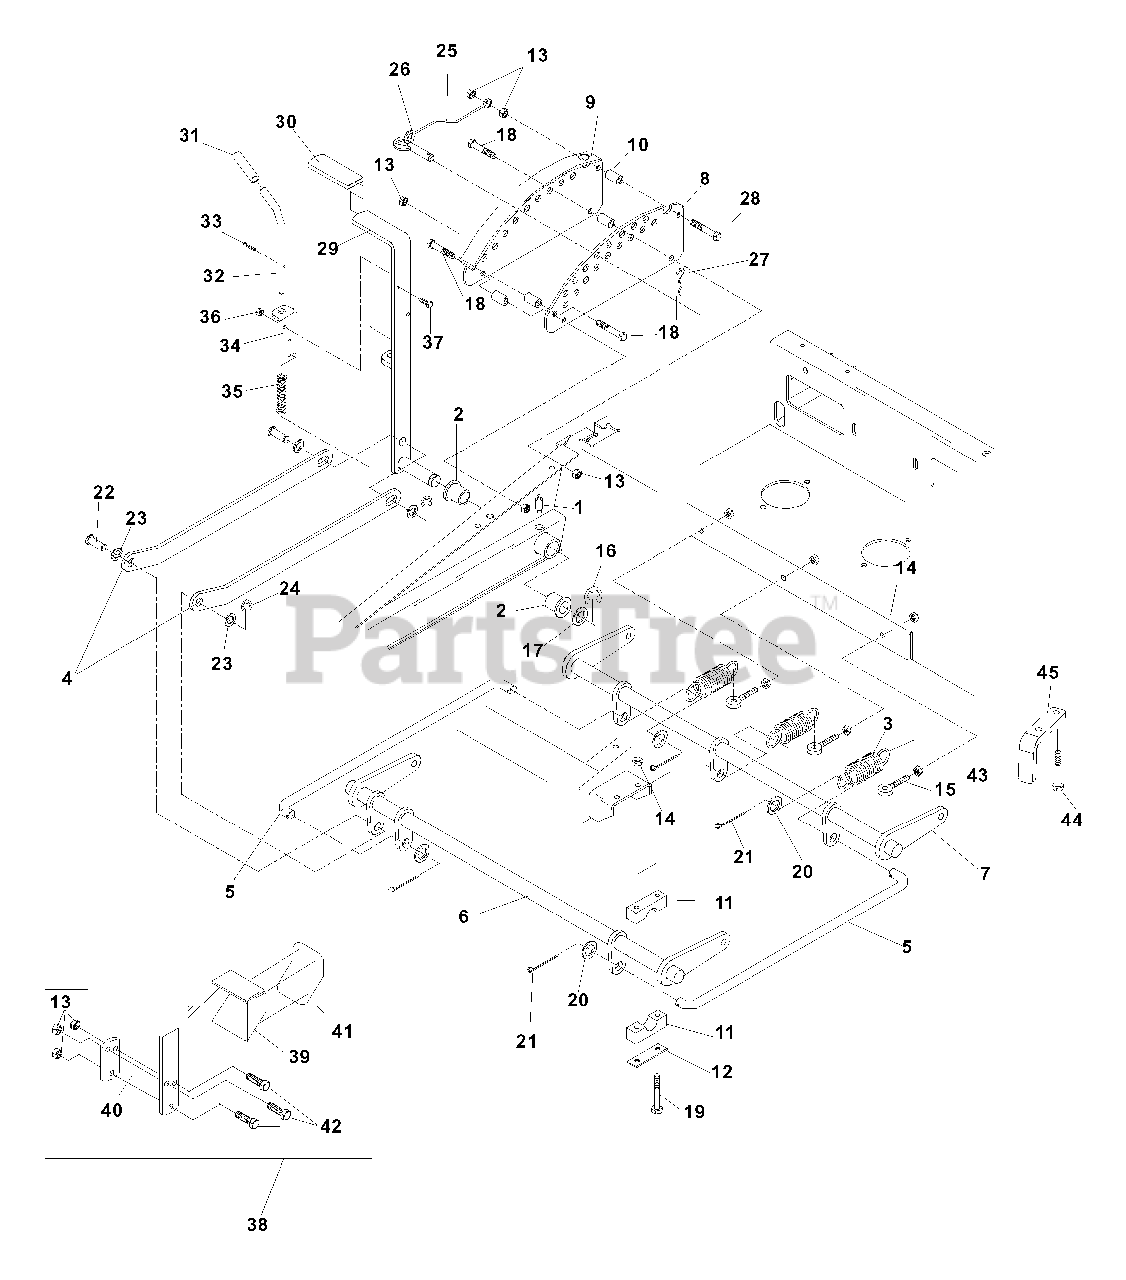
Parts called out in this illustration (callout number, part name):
1	ZERK, LONG
2	BUSHING, FLANGE
3	SPRING, DECK LIFT
4	LINKAGE, LIFT
5	LINK, CONNECTING
6	SHAFT, FRONT LIFT
7	SHAFT, REAR LIFT
8	PLATE, ADJUSTMENT
9	PLATE, ADJUSTMENT
10	SPACER, DECK LIFT
11	BLOCKS, PILLOW
12	PLATE, SUPPORT
13	NUT, 3/8C, NYLOC
14	NUT, 5/16 C, NYLOC
15	EYEBOLT, 5/16 C
16	E-RING, 7/8
17	BUSHING, MACHINE
18	HCS, 3/8 C x 2 1/2
19	HCS, 5/16 C x 2 3/4
20	WASHER, 5/8 , SAE
21	PIN, COTTER
22	PIN, CLEVIS 5/8
23	BUSHING, 5/8, MACHINE
24	E-RING, 5/8
26	PIN, HITCH
27	PIN, HAIR #4
28	HCS, 3/8 C x 2 3/4
29	LEVER, LIFT
30	CUSHION, HANDLE
31	GRIP, VINYL
32	PIN, LOCKING
33	PIN, GROOVED
34	PIN MOUNT, UPPER
35	SPRING, COMPRESSION
36	NUT, 1/4C, CENTERLOCK
37	HCS, 1/4 - 20 x 3/4, GR5
38	LIFT PEDAL, COMPLETE
39	PEDAL, LIFT
40	PLATE, TIGHTENING
41	PAD, ANTI-SKID
42	HCS, 3/8 C x 1 1/2
43	NUT, 5/16 C, WHIZ
44	BOLT, 3/8C x 1, THD FORMING
